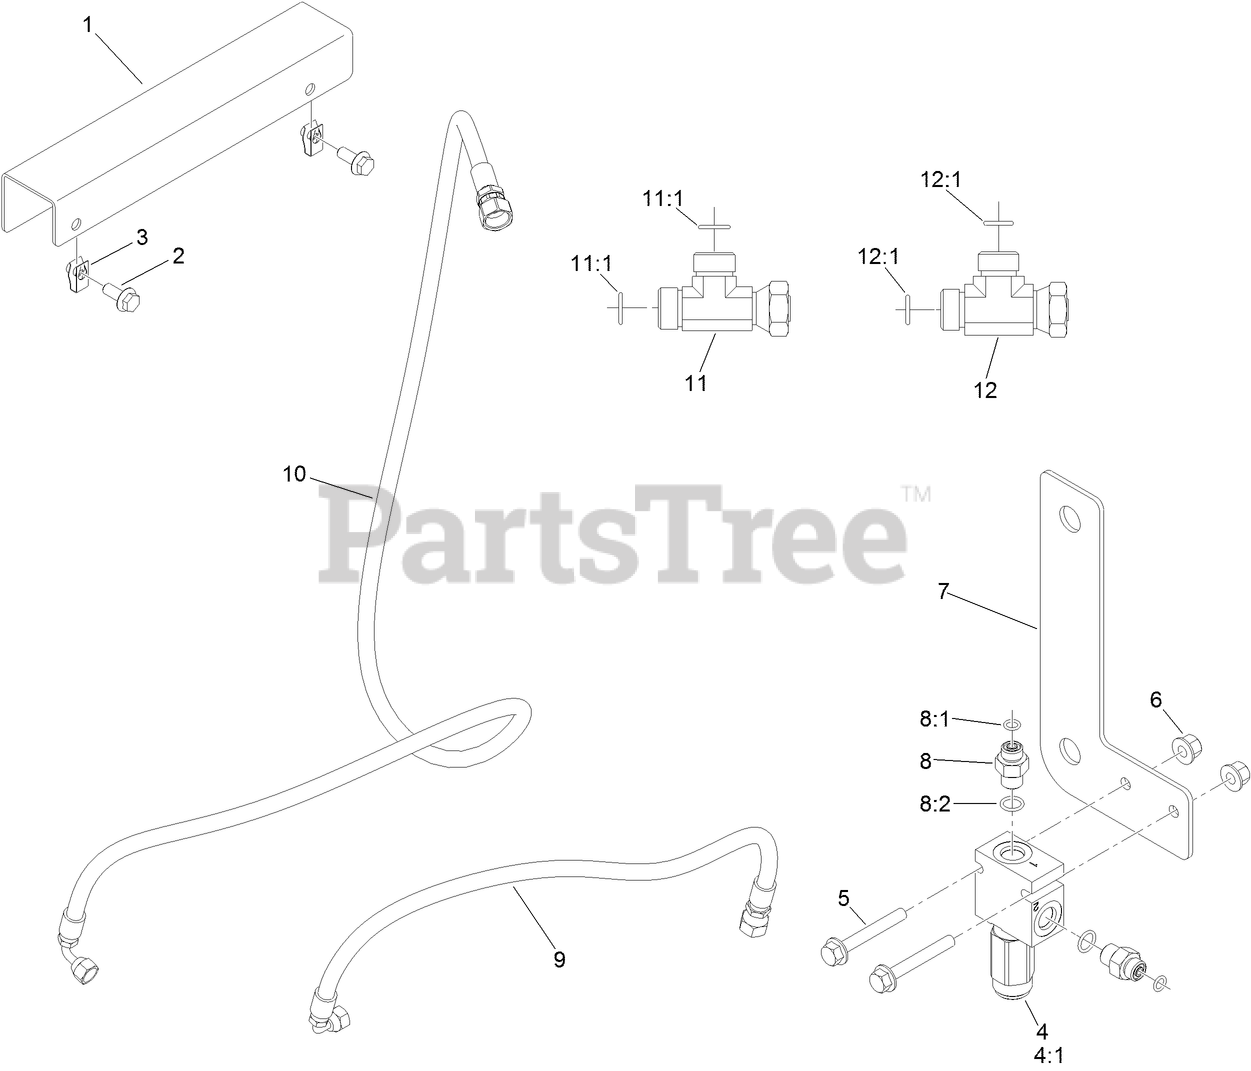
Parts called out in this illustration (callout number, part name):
1	PLATE-GUARD, WIRE
2	SCREW-HHF
4	VALVE-RELIEF
4:1	SEAL KIT
5	SCREW-HHF
6	NUT-FLANGE, NI
7	PLATE-MOUNT, VALVE
8	FITTING-STRAIGHT
8:1	O-RING
8:2	O-RING
9	HOSE ASM
10	HOSE ASM
11	FITTING-HYD, TEE
11:1	O-RING
12	FITTING-TEE, SWIVEL NUT
12:1	O-RING
